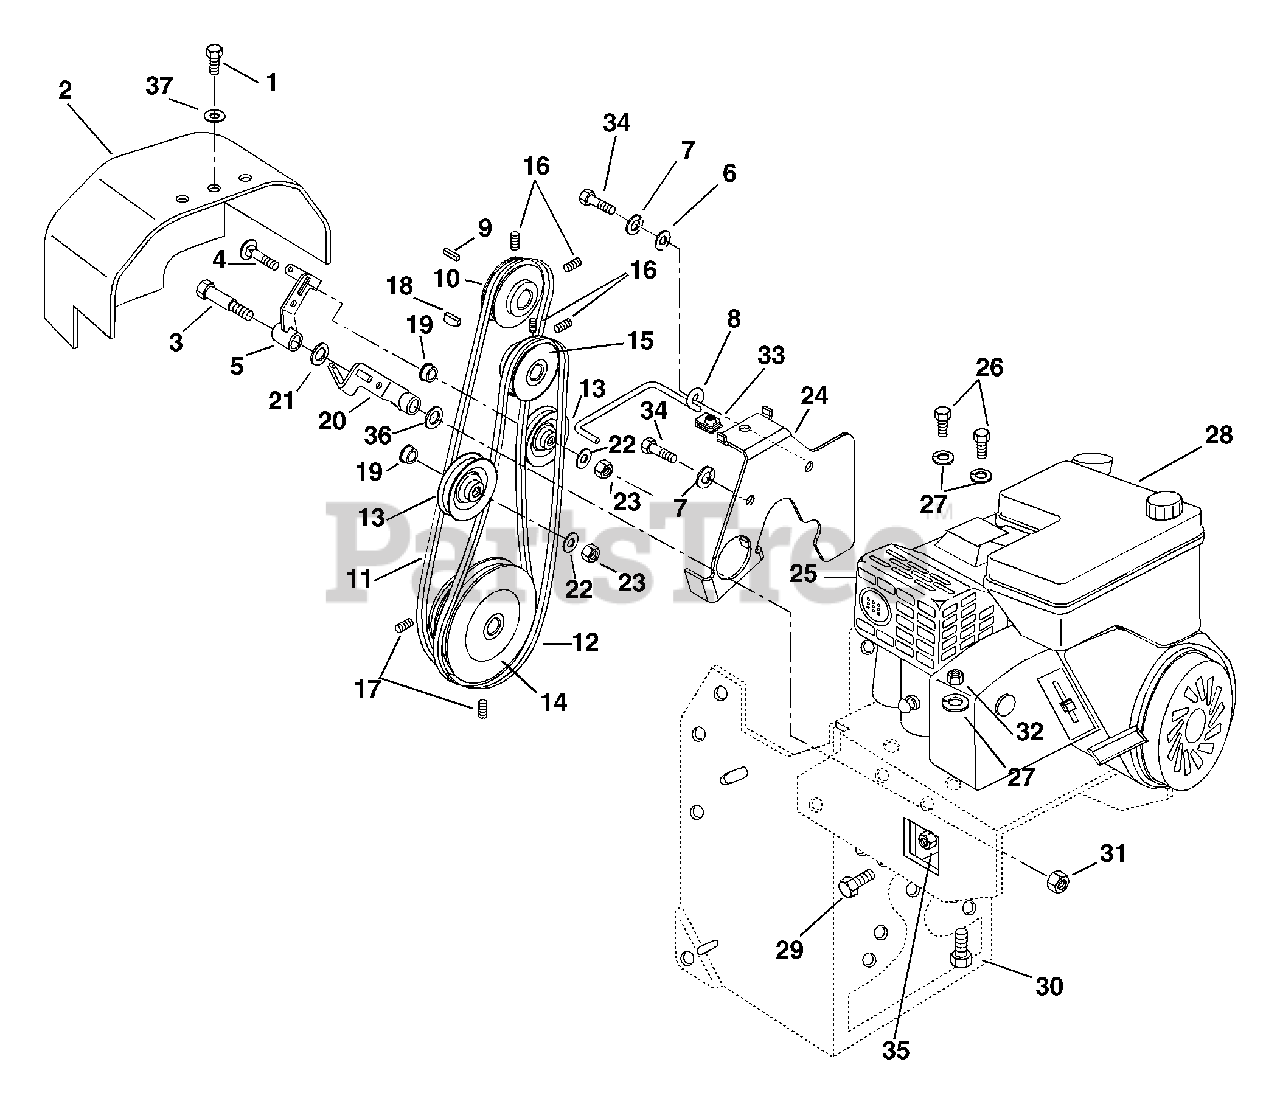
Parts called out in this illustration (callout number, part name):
1	@BLT-HEX .25-20X.75 GR5 YWZC
2	BELT COVER
3	SCR-SKTHD SHLDR .38-16X2.25
4	@BLT-RDHDSQNK .31-18X1.25 G5YZ
5	IDLER ARM FWD
6	@WSHR-FL-STL.312X.734X.065 YWZ
7	@WSHR-LK .31X.078 REG YWZC
8	FINGER, BELT
9	KEY-SQ .188X1.5X.187 SAE 8630
10	SHEAVE ASSEMBLY
11	V-BELT, 4L-WRAPPED
12	V-BELT, 3L-WRAPPED
13	IDLER
14	PLY-DBLV 5.50 X.75 W/KEY SALEM
15	SHEAVE, .50 ID X 2.00 OD
16	SCR-SET .25-20X.25 SKHCUPDL
17	SCR-SET .31-18X.38 SKHCUPDL
18	KEY-WDRF .125X.625X.250 SAE5
19	SPCR, BRG .315X.50X.688X.281
20	IDLER ARM REV.
21	WSHR-FL-STL .520X.827X.062 YZ
22	@WSHR-FL-STL.38X.875X.083 YWZC
23	@NUT-LK-CTR .31-18 YWZC
24	FINGER, BELT
25	MUFFLER SHIELD CE
26	@BLT-HEX .31-18X.75 GR5 YWZC
27	@WSHR-LK .31X.078 REG YWZC
28	ENGINE TEC 5HP OHV
29	@BLT-HEX .38-16X.75 GR5 YWZC
30	@BLT-HEX .31-18X1.75 GR5 YWZC
31	@NUT-LK-CTR .38-16 YWZC
32	@NUT-HEX .31-18 YWZC
33	NUT-SPEED U-TYPE .250-20
34	BLT-HEX .31-24X.75 YWZC GR5
35	NUT-LK TOP .375-16 GR C YWZC
36	@WSHR-FL-STL.531X1.06X.095YWZC
37	@WSHR-FL-STL.250X.56X.049 YWZC
